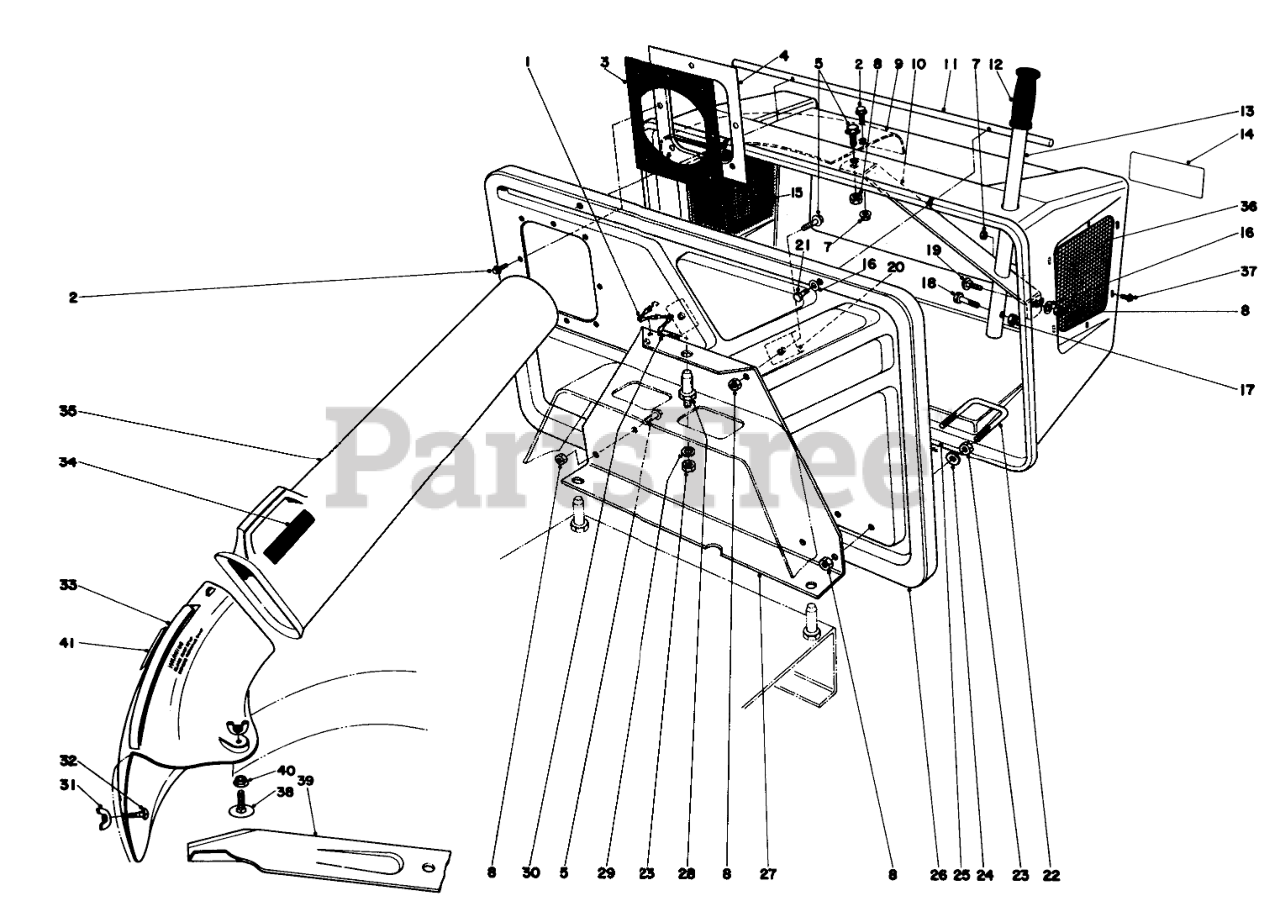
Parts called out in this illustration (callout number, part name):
1	6-LINK CHAIN W/HOOK
2	SCREW
3	INLET SEAL
4	FRAME SEAL
5	SCREW-HHF
7	NUT-LOCK, FLANGE
8	NUT-HEX, SIDE DEFORM
9	DEFLECTOR
10	HANDLE GUIDE
11	PIVOT ROD
13	HANDLE TUBE
14	EASY EMPTY BAG DECAL
15	Screen
16	WASHER-FLAT
17	NUT-HEX, SIDE DEFORM
18	SCREW-HH
19	SCREW-CARR
20	Retainer
21	SCREW-HH
22	LATCH
23	NUT-HEX
24	WASHER-FLAT
25	HOPPER
27	Plate Mounting
28	Pin-Mounting
29	WASHER-LOCK
30	HAIRPIN COTTER
31	NUT-WING
32	BOLT-CARR
33	Chute
34	Decal Duct
35	Duct (Incl. Ref. #34)
36	SCREEN
37	SCREW-HWH
38	Elevator Bolt
39	Blade
40	PAL NUT
41	Decal
